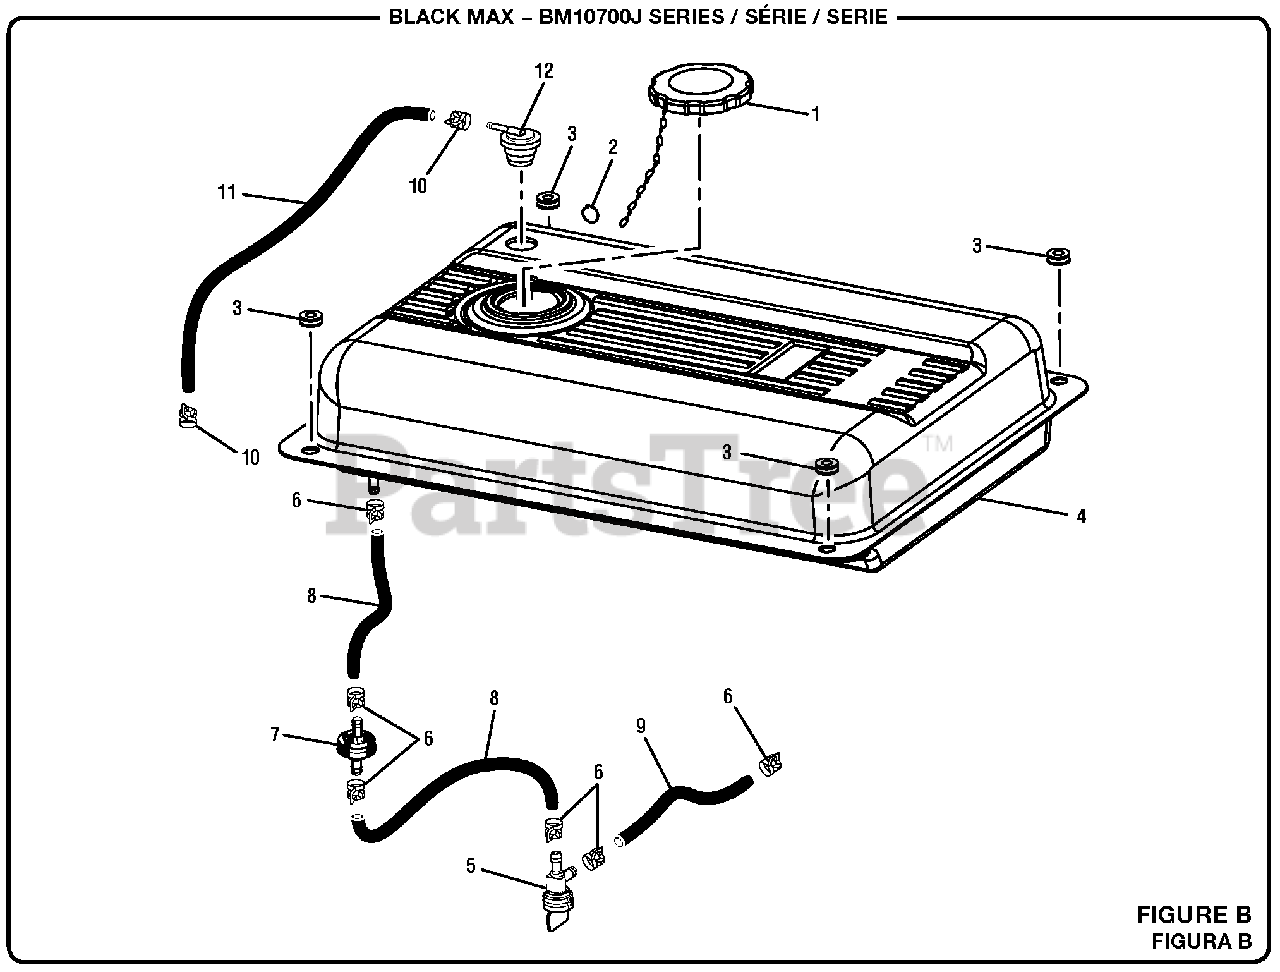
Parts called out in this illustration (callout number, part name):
1	Fuel Tank Cap
2	Ring Clip
3	Bushing w/Insert
4	Fuel Tank
5	Fuel Valve
6	Fuel Line Clamp (1/2 in)
7	Fuel Line Filter
8	Fuel Line (1/4 in)
9	Fuel Hose (1/4 in)
10	Fuel Line Clamp (7/16 in)
11	Vapor Hose
12	Vapor Vent
